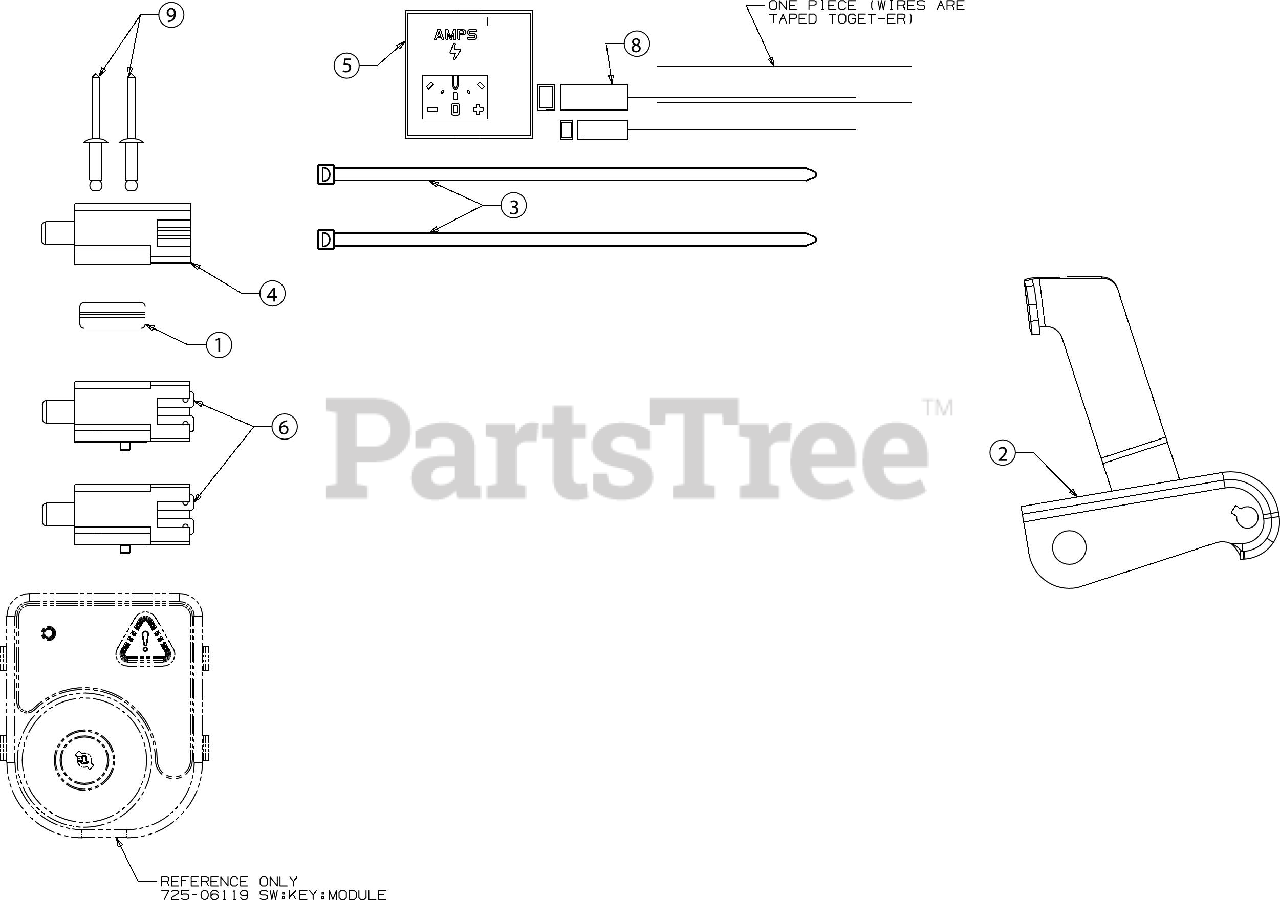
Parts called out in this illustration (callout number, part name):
1	PLATE-SWITCH
2	LATCH BRACKET
2	LATCH SPEED BRACKET
3	7" CABLE TIE
5	INDICATOR MONITOR
6	INTERLOCK SWITCH (NO/NC)
8	JUMPER HARNESS ASSEMBLY
9	POP RIVET .187 DIA
